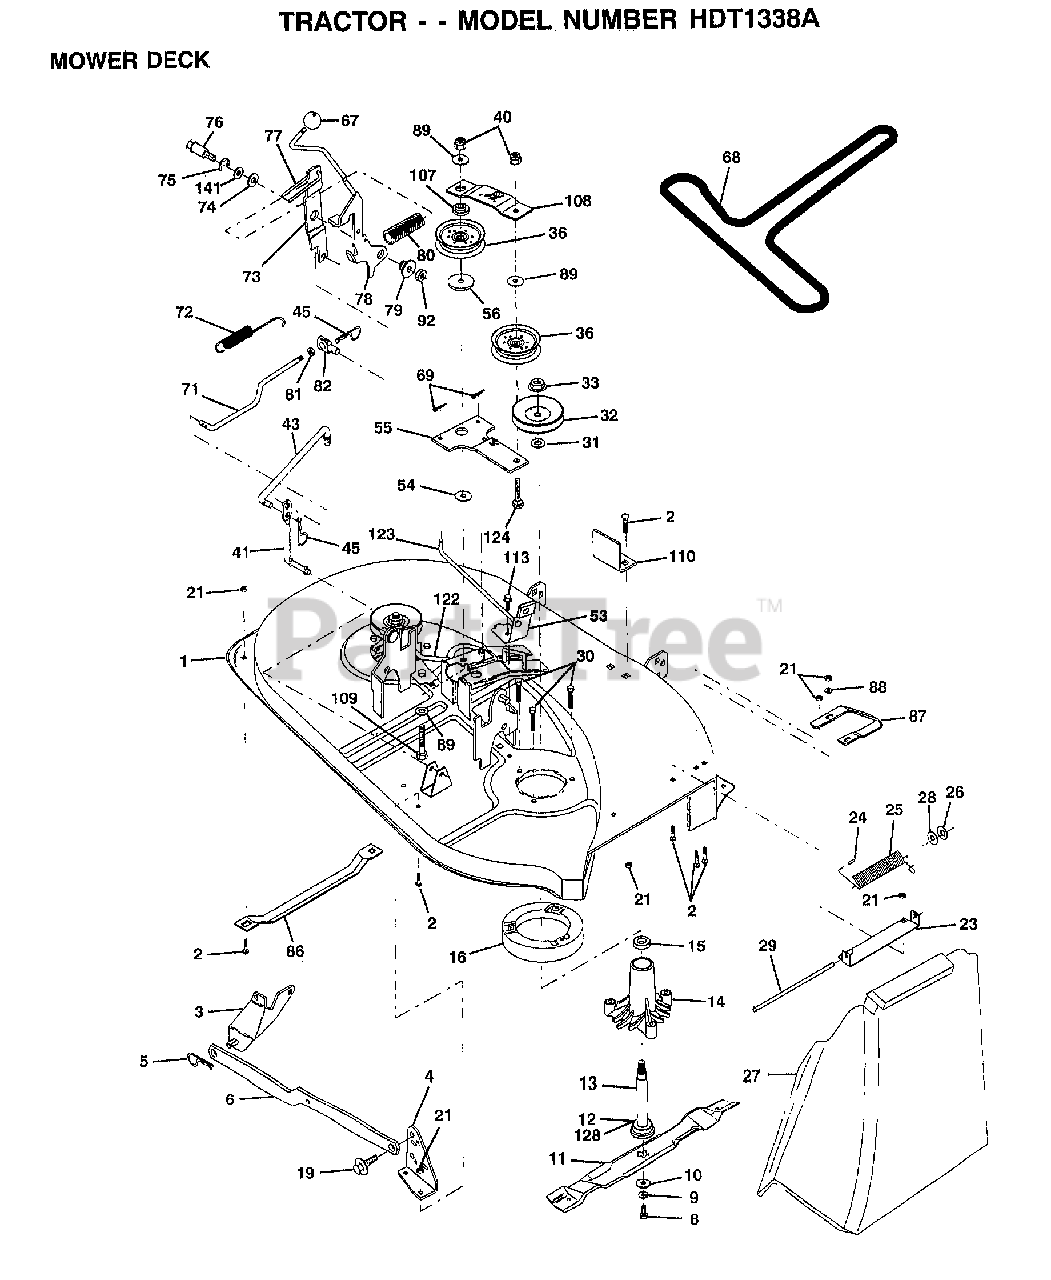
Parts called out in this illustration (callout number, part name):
2	BOLT
3	BRKT ASM SWAY BAR
4	BRKT DECK SW BAR
8	BLADE BOLT
10	WASHER.HARD.BLADE
11	"BLADE.38"" HIPERF"
12	BEARING.BALL
14	HSG ASM MANDREL
15	BEARING
16	STRIPPER RND MWR
19	BOLT SHD 5/16-18
23	BRKT DEFLECTOR
24	CAP-SLEEVE LT
25	SPRING TORSION
26	NUT PUSH M
27	DEFLECTOR-SHLD T
28	WASHER
30	"SCREW-THD ROLL,WA"
31	WASHER
32	PULLEY.MANDREL.38
34	BOLT
35	XMAS TREE FASTNER
36	FLAT IDLER PULLEY
41	PIVOT ROD
43	CLUTCH ROD SECOND
44	GUARD MAND LH BLK
45	RETAINER M
53	BRAKE ASM
54	HARDENED WASHER
55	IDLER ARM ASSY
56	SPACER RETAINER
58	SPRING TORSN BRAK
59	GUARD IDLER TUV
67	KNOB.RD.7/16-14
68	BELT.V.T-PATH
71	ROD CLUTCH 38/42
72	RETURN SPRING
73	CLUTCH ARM SECOND
74	WASHER
75	RING
76	SHOULDER BOLT
77	SPRING KEEPER
78	LEVER.ASM.CLUTCH
79	BUSHING
80	SPRING.CLUTCH.MWR
81	NUT
82	TRUNION ADJ
86	RUNNER-LH M
87	RUNNER RH
88	WASHER M
89	WASHER GT
92	NUT
107	RETAINER SPACER
108	IDLER ARM STIFF
109	BOLT
110	UPSTOP DECK FT 38
111	BRACKET.GWHL.LH.
113	SCREW
122	BRAKE ROD LH
123	BRAKE ROD RH
124	BOLT
128	WASHER.FELT.
141	WASHER .T
